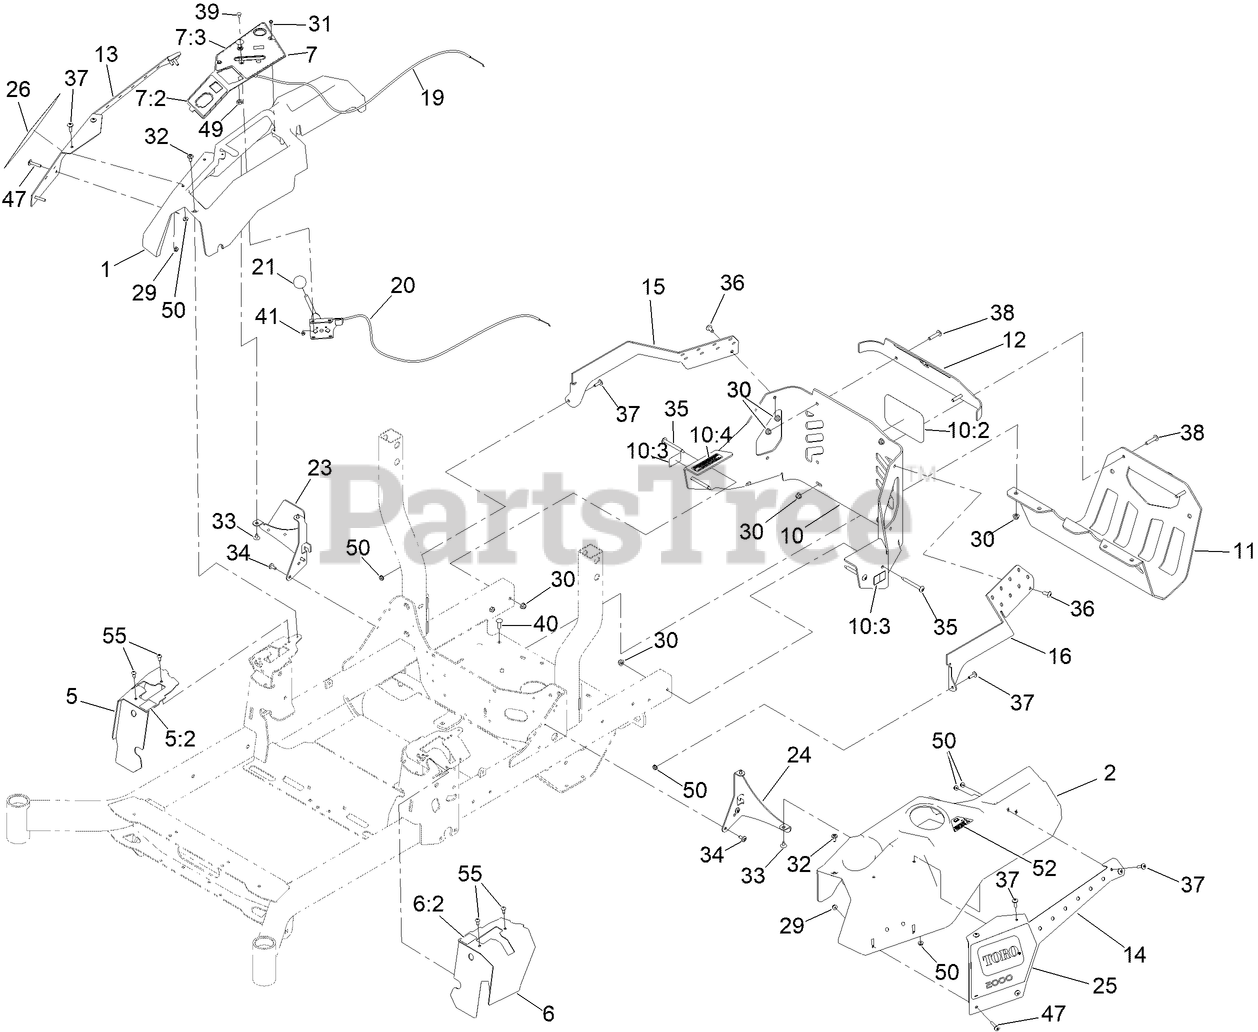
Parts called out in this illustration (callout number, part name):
1	CONSOLE-RH
2	CONSOLE-LH
5	COVER - CONTROL, MOTION
5:2	DECAL-MOTION CONTROL
6	COVER - CONTROL, MOTION
6:2	DECAL-MOTION CONTROL
7	CONTROL PANEL ASM
7:2	DECAL-PANEL, CONTROL
7:3	DECAL-PANEL, CONTROL
10	REAR GUARD ASM
10:2	DECAL
10:3	DECAL-WARNING
10:4	DECAL-ARRESTOR, SPARK
11	GUARD-MUFFLER [BLACK]
12	TRIM-UPPER REAR
13	COVER,POD RH
14	COVER [BLACK]
15	BRACKET-GUARD, RH
16	BRACKET-GUARD, LH
19	CABLE-CONTROL, CHOKE
20	CABLE-CONTROL, THROTTLE
21	KNOB-BALL
23	SUPPORT-CONSOLE, RH
24	BRACKET-CONSOLE, LH
25	DECAL-2000, LH
26	DECAL-2000, RH
29	NUT-HF
30	NUT-HF, NI
31	SCREW-HWH
32	SCREW-SHOULDER
33	SCREW-TORX
34	SCREW-TORX
35	SCREW-TORX
36	SCREW-TORX
37	SCREW-TRUSS
38	SCREW-TORX
39	BOLT-CARR
40	SCREW-CARR
41	NUT-LOCK, NI
47	SCREW-TRUSS
49	NUT-HJ
50	NUT-KEPS
52	DECAL-FILL, FUEL
55	SCREW-TPH THD FORM
